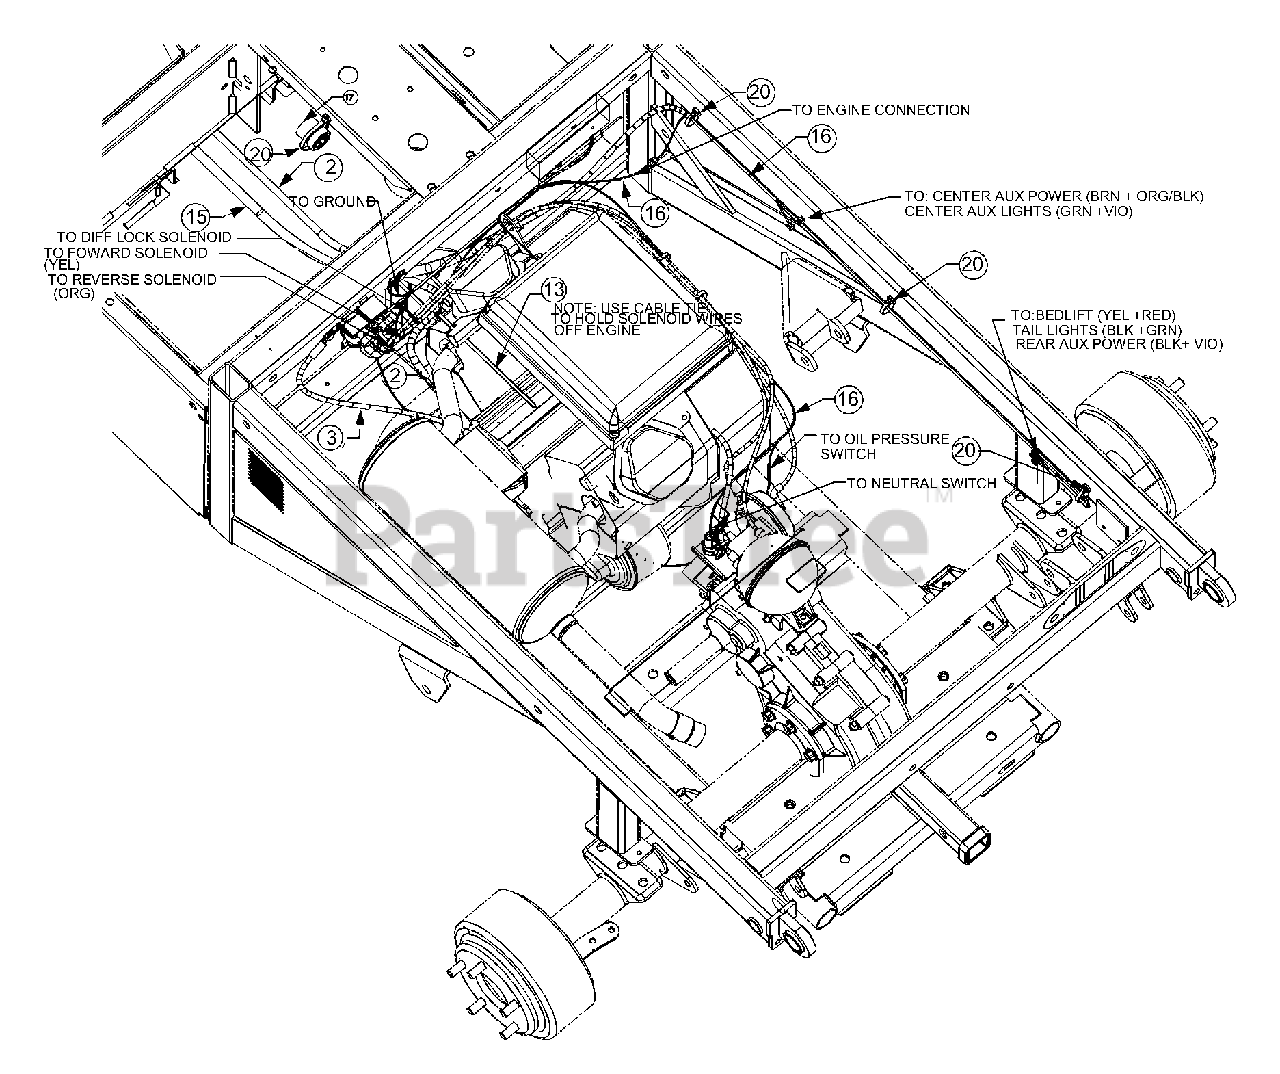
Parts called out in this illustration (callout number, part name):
2	Harness Assembly, Starter
3	Harness Assembly, Motor Ground
13	Cable Tie, 3/16 x .05 x 7.4
15	Harness, Utility Main
16	Harness, Motor
17	Control, Reverse
20	Cable Tie, .19 x 8.39 Tree Mount
